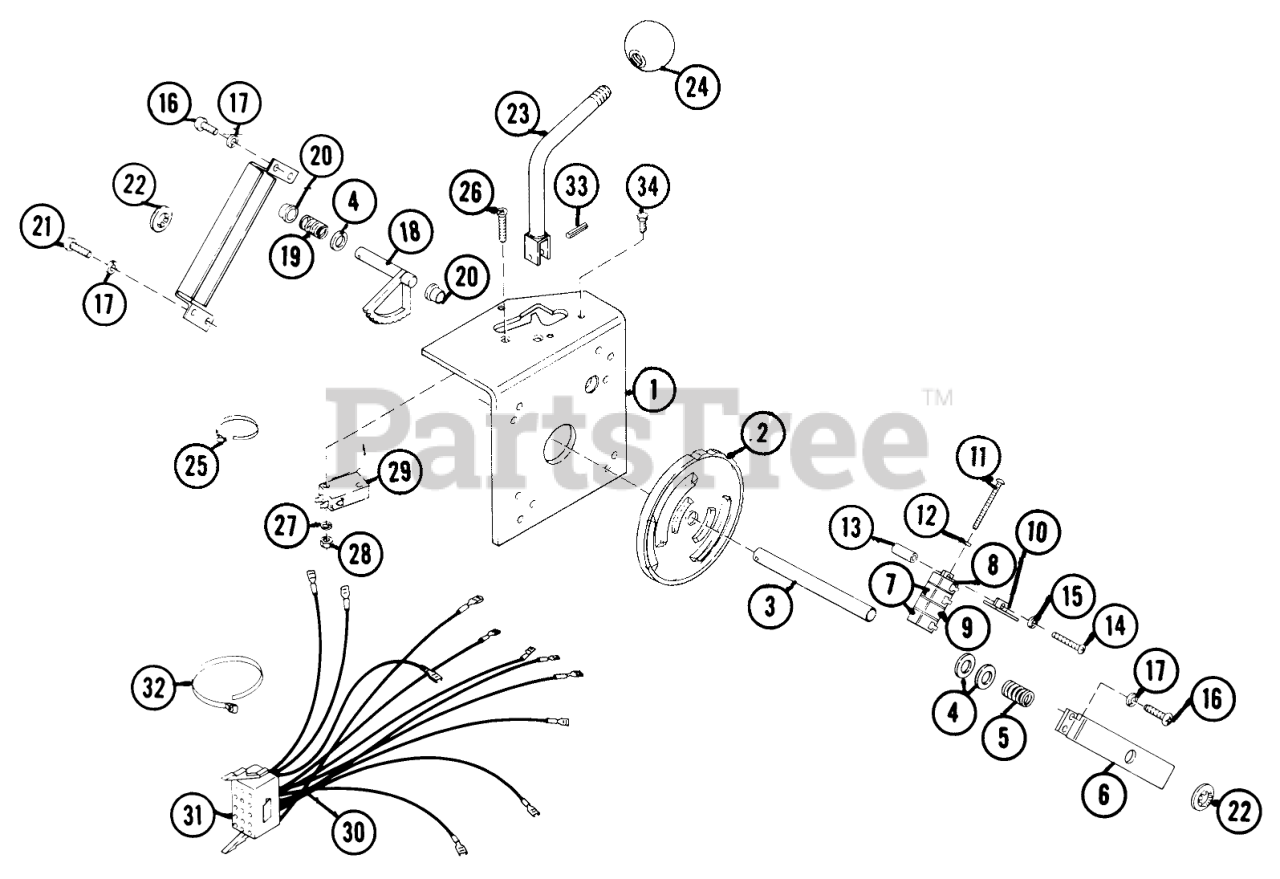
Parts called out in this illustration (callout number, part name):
4	Washer 3/8 Narrow
6	Switch Mounting Bracket
10	Switch Holding Bracket
13	Spacer
14	Screw, Phillips Pan Hd. Thd. Cutting #6-32 x 3/4
15	Lockwasher, Int. Tooth #6
16	Screw, Phillips Pan Hd. Thd. Cutting #8-32 x 3/8
17	Lockwasher, Int. Tooth #8
21	Mach. Screw, Phillips Pan Hd. #8-32 x 1/4
26	Screw, Phillips Flat Hd. #4-40 x 3/4
27	Spring Lockwasher #4
33	Pin, Throttle
34	Screw, Thd. Rolling #8-32 x 5/8 Dull Black
